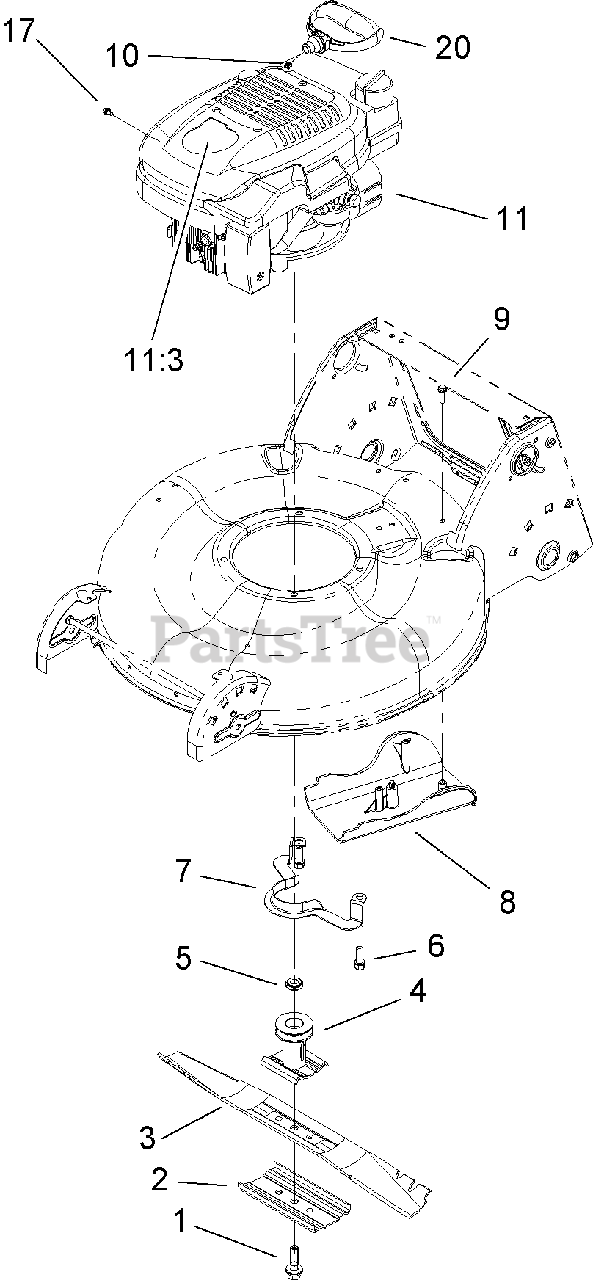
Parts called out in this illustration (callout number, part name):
1	BOLT-BLADE
2	SUPPORT-BLADE
3	BLADE-21 INCH
4	BLADE DRIVER ASM
5	Spacer-Driver
6	SCREW
8	COVER-BELT
9	SCREW-HWH
10	STOP-ROPE
11:3	DECAL-RECOIL
17	SCREW-HWH
20	HANDLE-RECOIL
